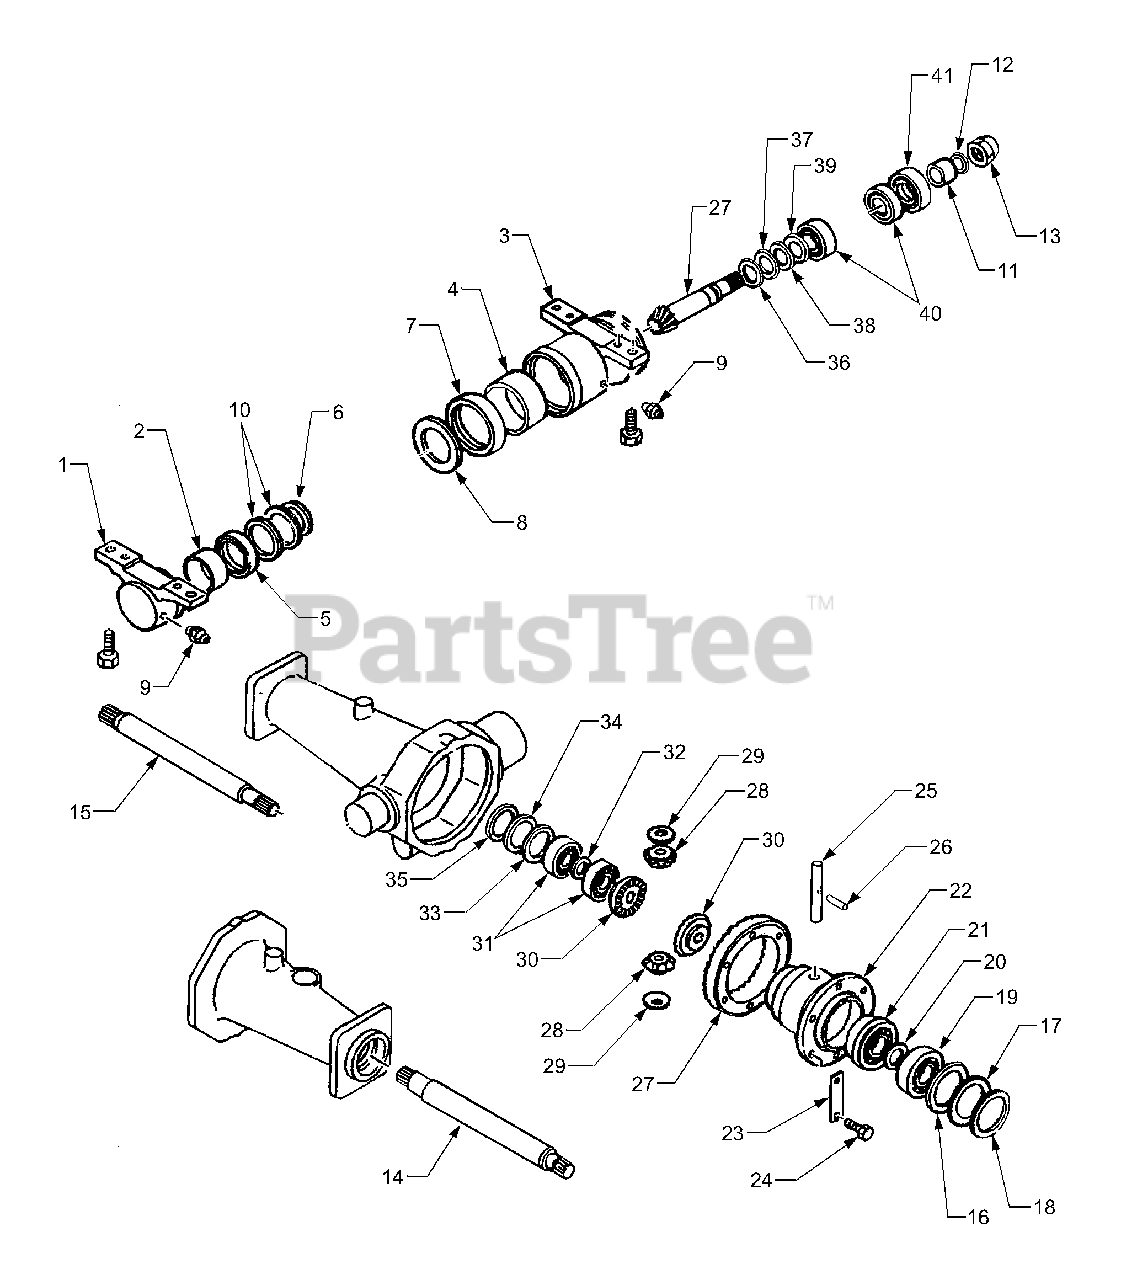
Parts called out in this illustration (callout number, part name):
1	Mtg. Bracket, Axle Front
3	Mtg. Bracket, Axle Rear
6	Washer, Thrust
8	Washer, Thrust
9	Fitting, Grease
10	Shim Kit, Service Only
14	Shaft, Differential LH
15	Shaft, Differential RH
19	Bearing, Ball
21	Bearing, Ball
22	Housing, Differential
23	Plate, Locking
24	Bolt, M8 x 16
25	Shaft, Pinion
27	Gear Set, Ring and Pinion
28	Gear, Pinion
29	Washer, Thrust
30	Gear, Differential
31	Bearing, Ball
36	Washer, Thrust
40	Bearing, Tapered Roller
